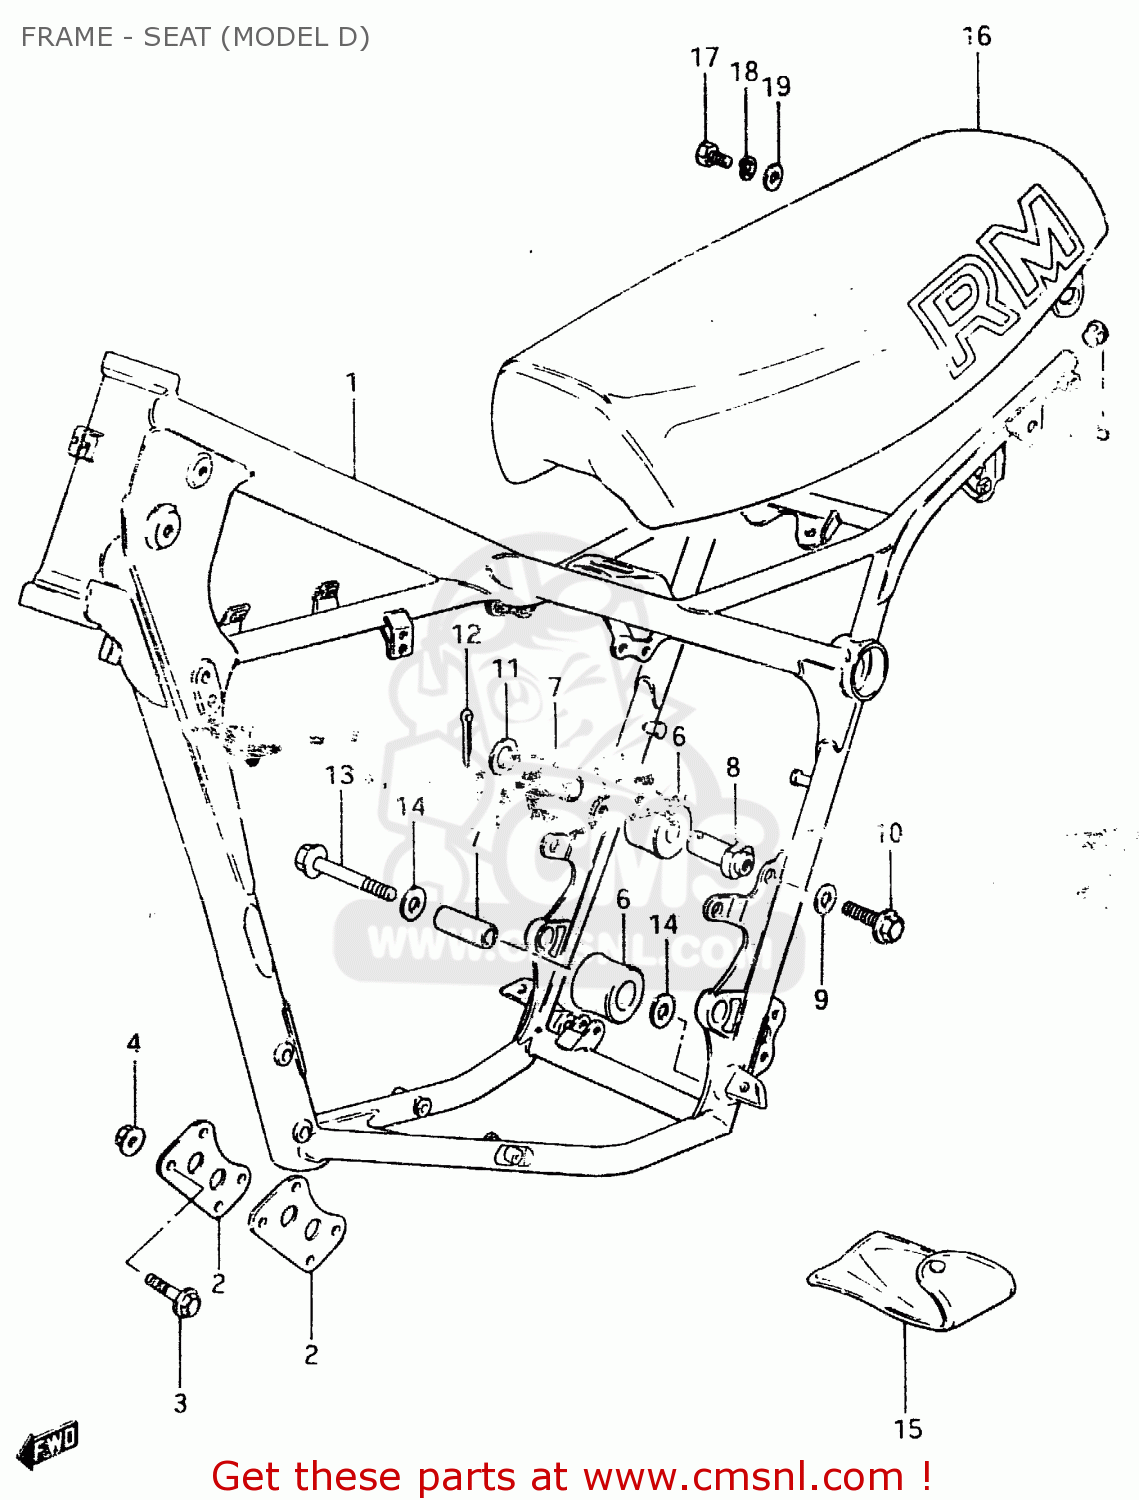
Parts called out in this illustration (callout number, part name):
1	FRAME
2	PLATE,ENGINE MOUNTING
3	BOLT(8X75)
4	NUT
5	PLUG(OD:17)
6	ROLLER,CHAIN LENGTH CONTROL
7	SPACER,CHAIN LENGTH ROLLER
8	BOSS,CHAIN LENGTH ROLL
9	WASHER
10	BOLT
11	WASHER
12	PIN 25X20
13	BOLT(8X45)
14	WASHER
15	TOOL SET
16	SEAT ASSEMBLY
17	BOLT
18	LOCK WASHER
19	WASHER
